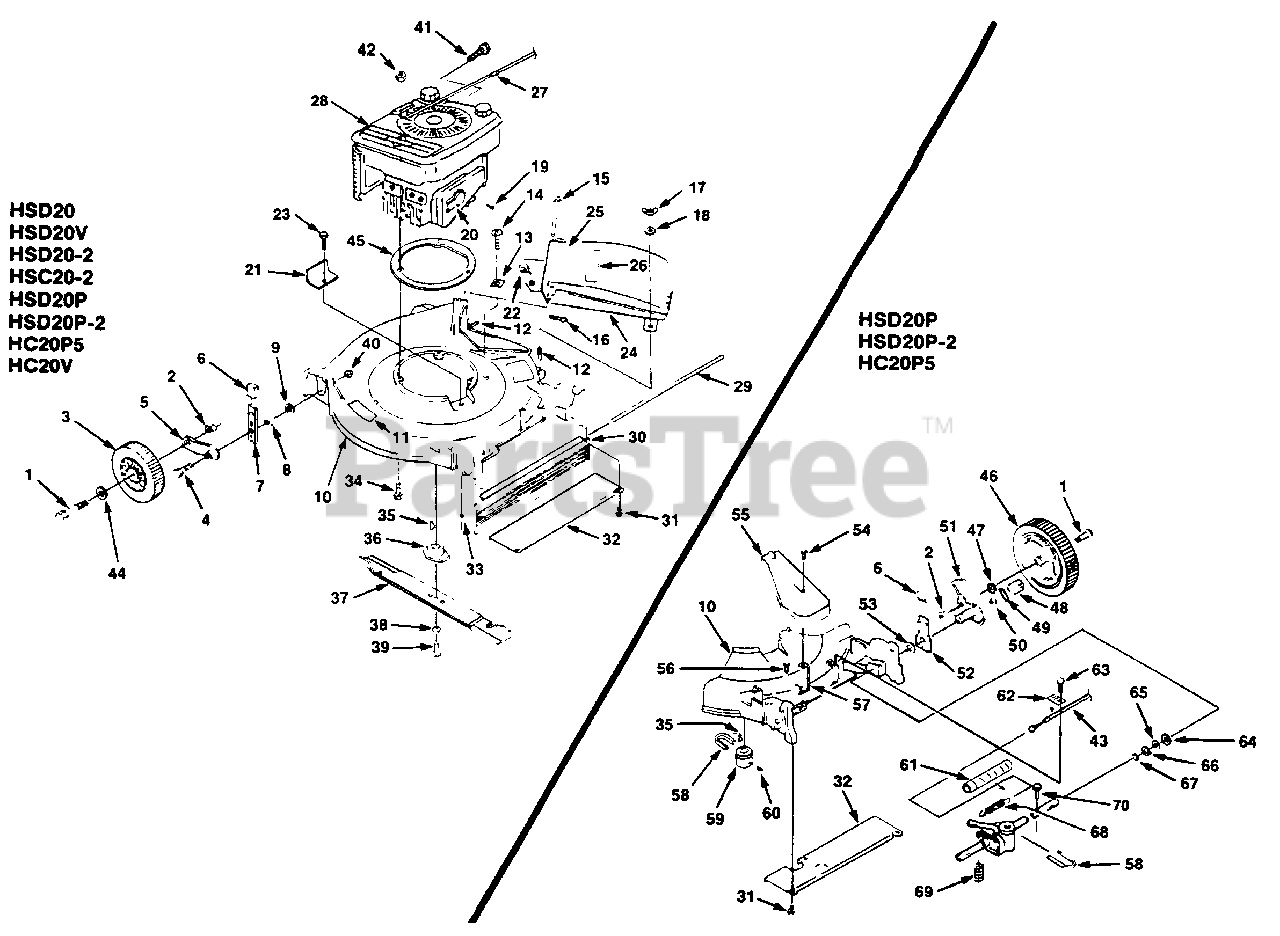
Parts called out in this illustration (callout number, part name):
1	BOLT- Axle
2	NUT
3	WHEEL & TIRE
4	BOLT- Height adj.
5	ARM- Wheel adj.
6	KNOB- Indexing spring
7	INDEX SPRING & PIN
8	SPACER- Wheel hgt adj.
9	WASHER- Flat (5/16")
11	DECAL- Warning
13	BRACKET- Rear bagger
14	SCREW- (1/4-20 x 1/2")
15	PIN- Hinge
16	PIN- Cotter
17	NUT- Wing
18	WASHER- Plain (1/4")
19	SCREW- (#8-32 x 3/8")
20	DEFLECTOR
21	COVER- Belt opening
22	SPRING- Chute
23	SCREW- (1/4-20 x 1/2")
24	COVER- Discharge
25	DECAL-CPSC
26	DECAL- Danger
27	STOP- Rope
28	ENGINE
29	ROD- Drag flap
30	FLAP- Drag
31	SCREW- (1/4-20 x 3/4")
32	Cover- Rear
33	NUT- Lock (1/4-20)
34	SCREW- (3/8-16 x 1 1/2")
35	KEY- Woodruff
36	ADAPTER- Blade
37	BLADE- (20")
38	WASHER- Lock (3/8")
39	SCREW- (3/8-24 x 1/2")
40	NUT- Flange (5/16-18)
41	SCREW- (10-32 x 3/8")
42	NUT- Lock (1/4-20)
43	CONTROL- Traction
44	WASHER
45	RING- Engine
46	WHEEL & TIRE
48	PINION (L.H.)
49	PIN- Drive
51	SUPPORT- Drive wheel
52	INDEX SPRING & PIN
53	SPACER- Rear hgt. adj.
54	SCREW- (1/4-20 x 3/4")
55	COVER- Drive
56	SCREW- (1/4-20 x 9/16")
57	BRACKET- Gearbox
58	BELT- Drive
59	PULLEY- Drive
60	SCREW- Set (1/4-20 x 3/8")
61	COVER- Spring
63	SCREW- Hex (1/4-20 x.518)
67	RING- Eaton
68	SPRING- Extension
69	SPRING- Compression
70	PIN- Roll
